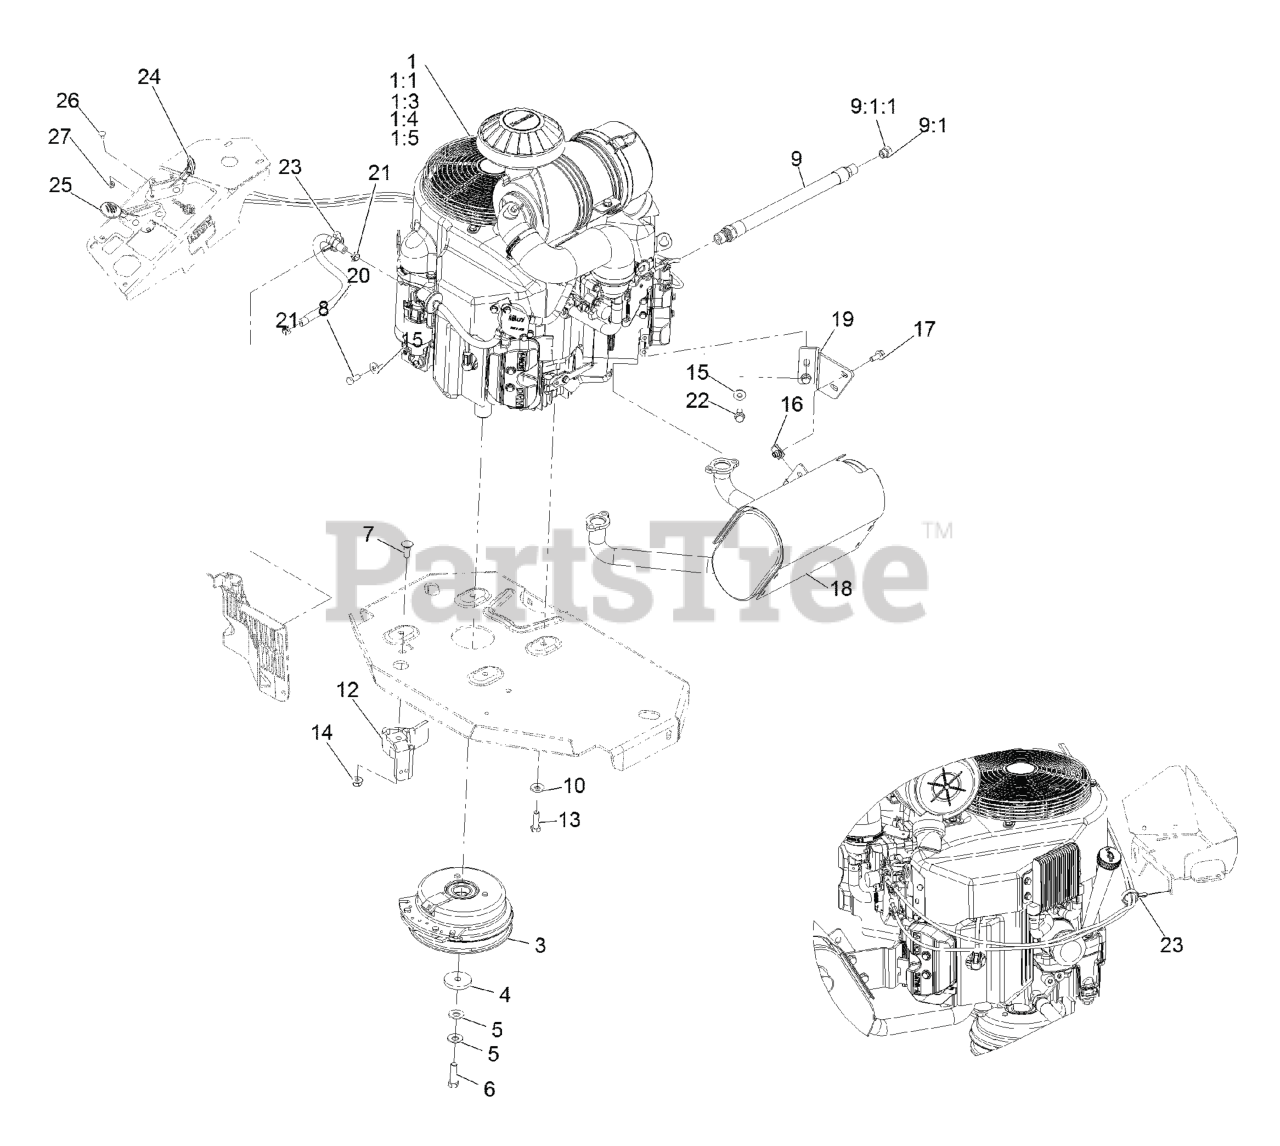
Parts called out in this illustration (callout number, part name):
1:1	Kawasaki 49065-2078 Engine Oil Filter
1:3	Kawasaki 49019-7001 Fuel Filter
1:4	Kawasaki 11013-7039 Safety Filter
1:5	Kawasaki 11013-7038 Air Filter
3	CLUTCH KIT
4	WASHER-CLUTCH
5	WASHER-SPRING
6	SCREW-HH 7/16-20 X 1 1/2 W/LOCTITE
7	SCREW-CARR
8	SCREW-HH
9	ENGINE OIL DRAIN HOSE ASM
9:1	PLUG-HH
9:1:1	O-RING
10	WASHER-BELLEVILLE
12	CLUTCH-ANCHOR
13	SCREW-HH
14	NUT-HF, NI
15	WASHER-SPRING
17	SCREW-HHF
18	MUFFLER
19	BRACKET-MUFFLER
20	HOSE-FUEL
21	CLAMP-HOSE
22	SCREW-HHF
23	CLAMP-HOSE
24	ASM, CHOKE CABLE
25	ASM,THROTTLE CABLE
26	BOLT-CARR
27	NUT-LOCK, NI
